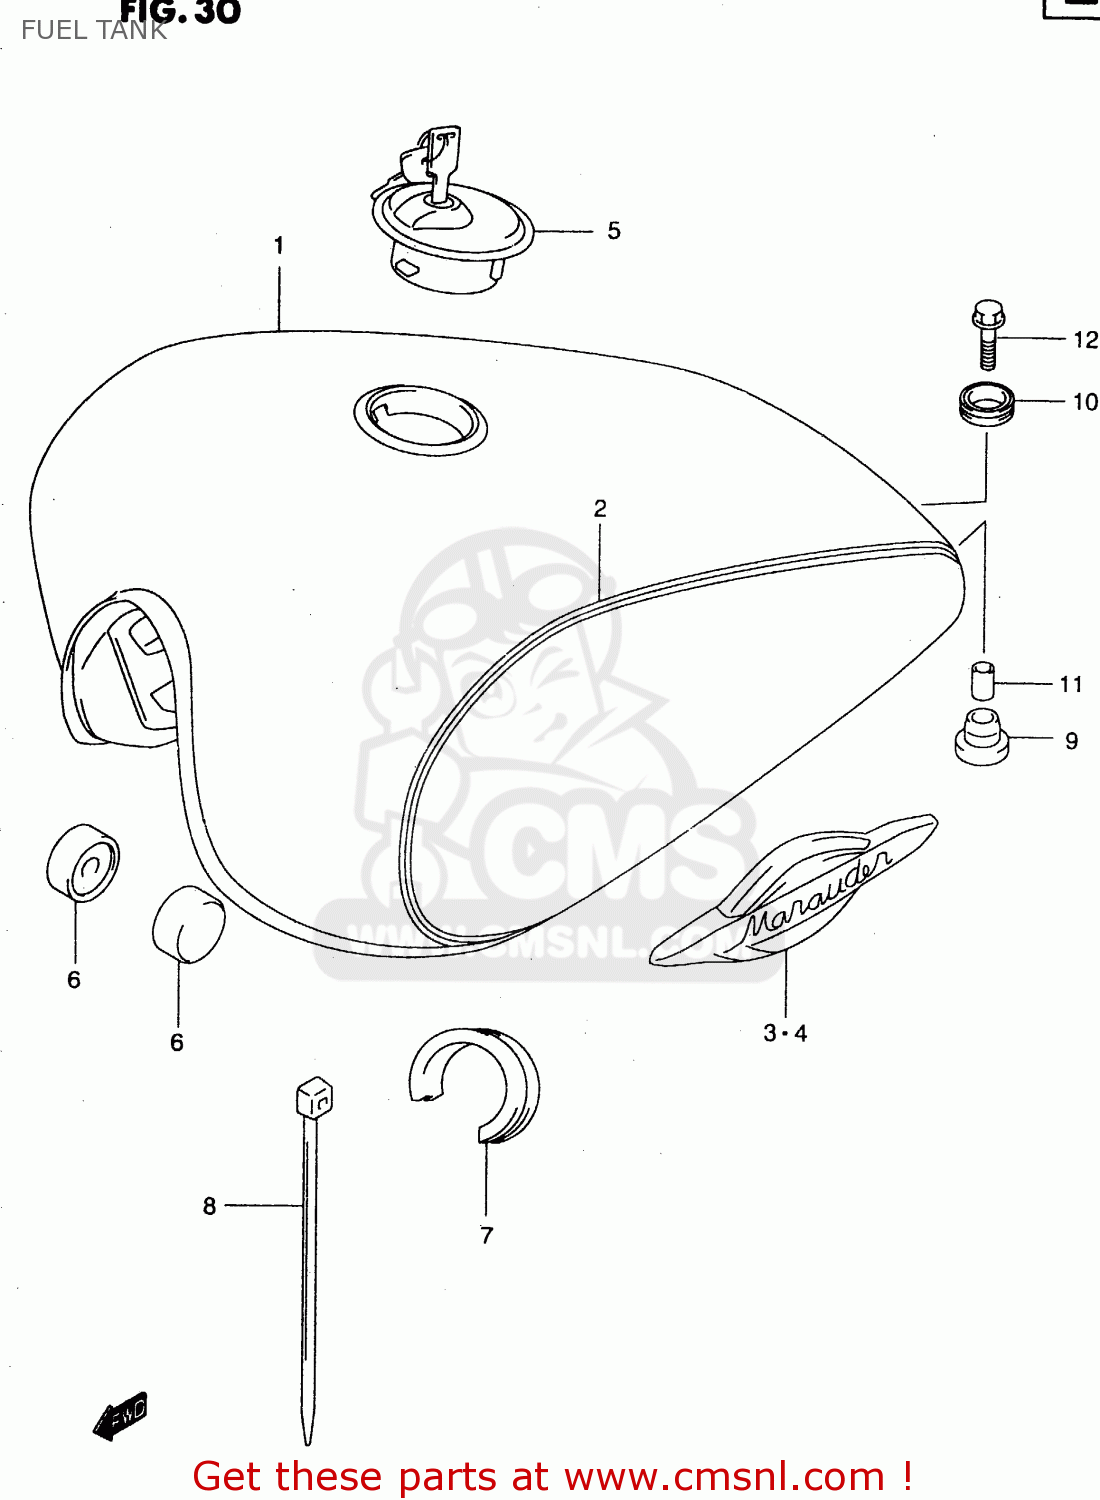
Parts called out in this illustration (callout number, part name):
1	TANK ASSEMBLY,FUEL
2	TAPE SET,FUEL TANK
3	EMBLEM,FUEL TANK,RIGHT
4	EMBLEM,FUEL TANK,LEFT
5	CAP SET,FUEL TANK
6	CUSHION
7	CUSHION,FUEL TANK SIDE
8	CLAMP(L:250)
9	CUSHION
10	CUSHION,FUEL TANK RR
11	SPACER(6.5X9X18)
12	BOLT
